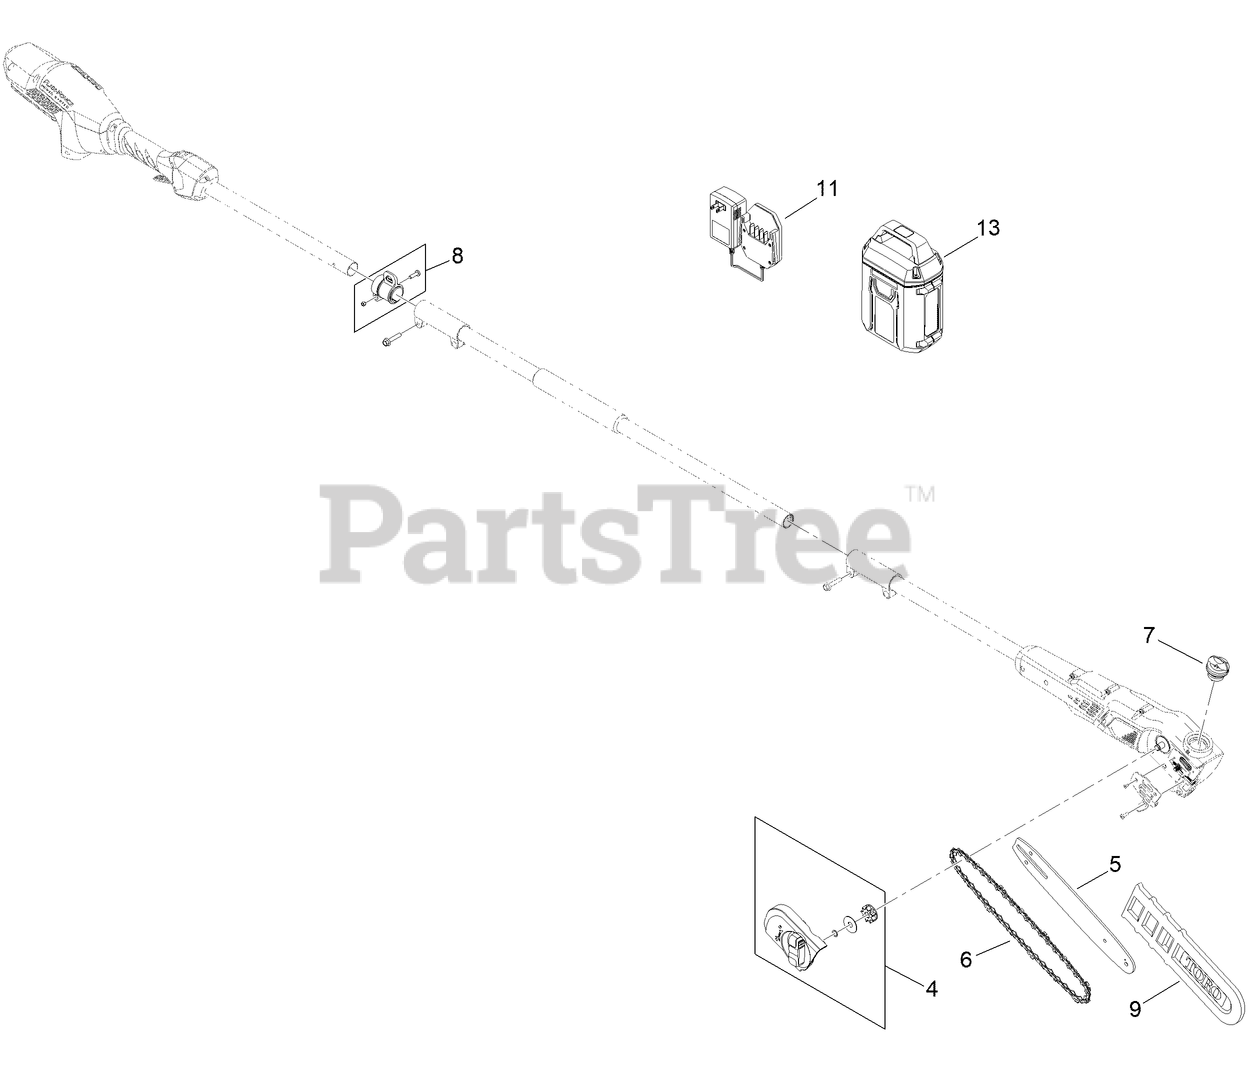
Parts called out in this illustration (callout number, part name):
4	TENSIONER ASM
6	CHAIN
7	CAP-OIL
8	COLLAR-STRAP
9	SLEEVE-BAR
11	CHARGER-BATTERY, 60V 1 AMP
13	BATTERY-60V 2.0AH
